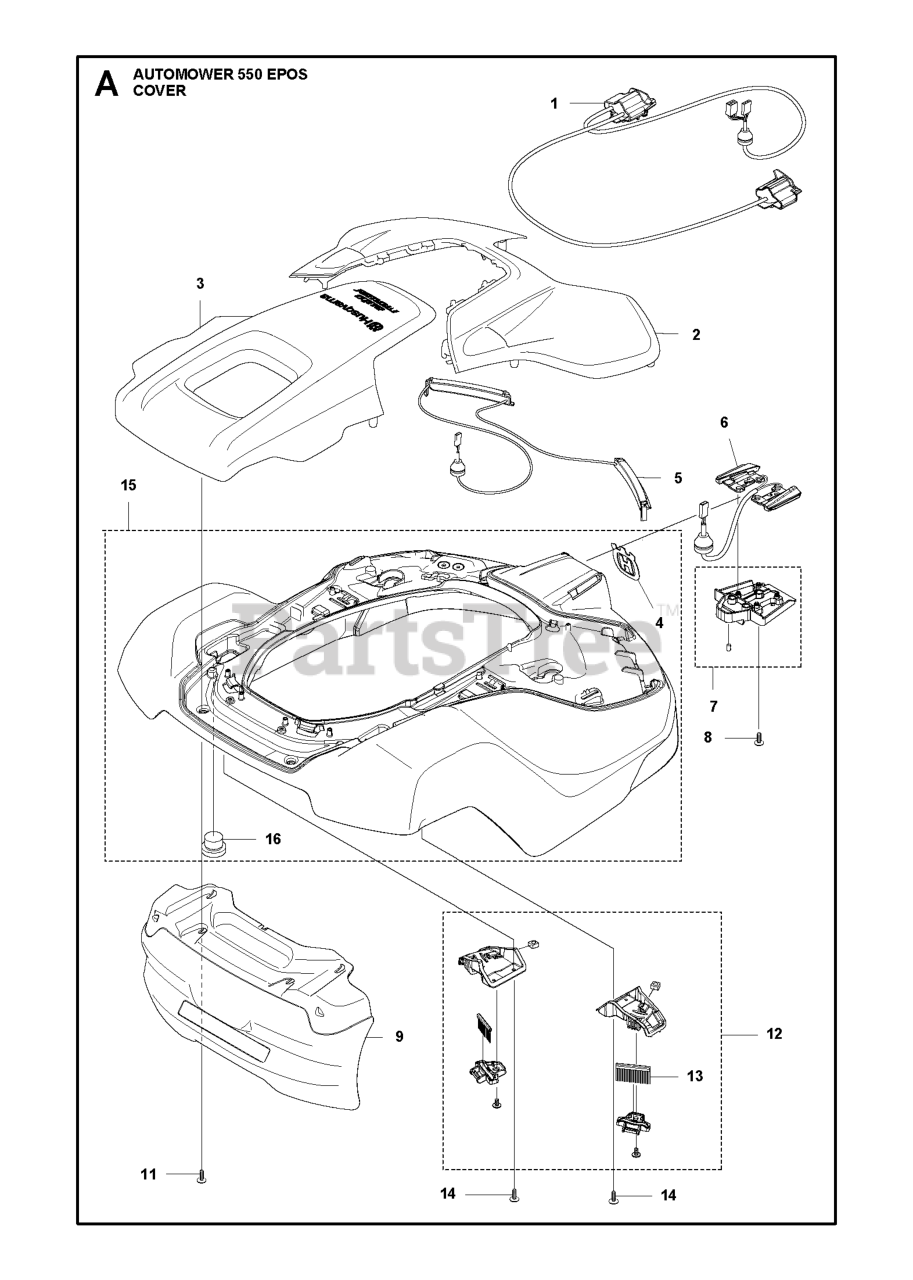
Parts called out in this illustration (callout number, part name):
1	WIRING ASSY ULTRASONIC
2	FRONT COVER TOP ORANGE
3	REAR COVER TOP GREY
4	DECAL HUSQVARNA CROWN HEIGHT 5
5	WIRING ASSY LED LIGHT WIRING O
6	CABLE ASSY CHARGING PLATE
7	HOLDER ASSY MAGNET
8	SCREW 14MM
9	BUMPER REAR
11	SCREW ITXPANT
12	BRUSH KIT 430/450
13	WHEEL BRUSH REFILL KIT
14	SCREW 14MM
15	BODY ASSY
16	CAP SNAPLOC
